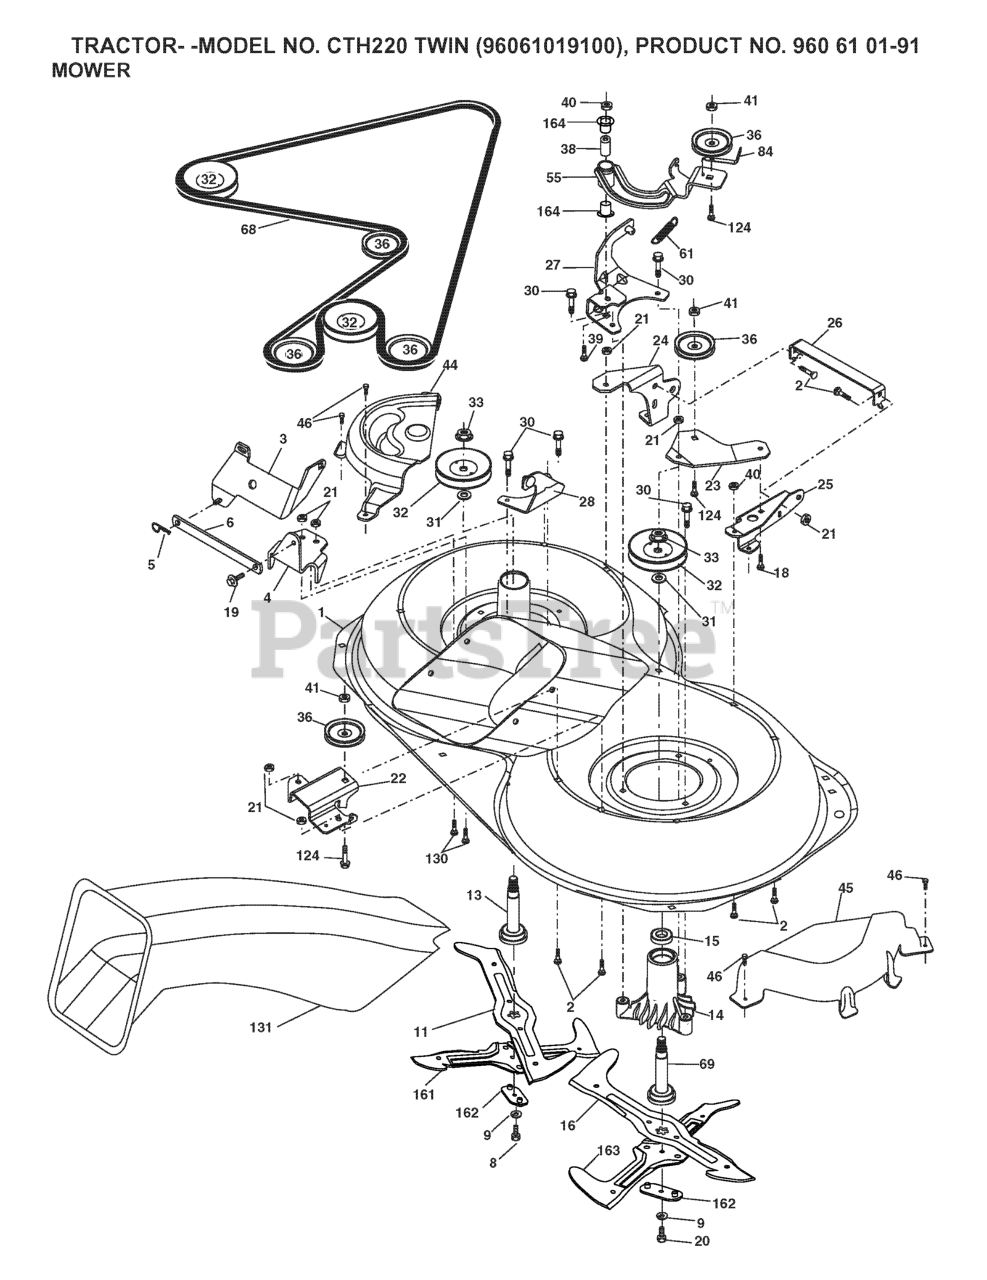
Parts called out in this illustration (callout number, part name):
1	Housing Asm. Mower 107 CRD
2	RP BOLT 5/16-18 X3/4 ZN/YEL GR
5	RETAINER-SPRNG RB
6	BAR.SWAY.92.CRD
8	BOLT.3/8-24X1.25 GR8
9	LOCKWASHER
11	BLADE.3N1.LH.CRD
13	SHAFT ASM VENT
14	HOUSING.MANDREL.VENTED (MACHD)
16	BLADE.3N1.RH.CRD
18	BOLT
19	BOLT SHD 5/16-18
20	BOLT.3/8-24X1.25GR8. LHTHRD
21	LOCKNUT
22	BRACKET.IDLER.RR.107.CRD
24	BRACKET
25	BRACKET RF
26	SUPPORT
28	BRACKET
30	SCREW, WASHER HEAD
31	WASHER.SPACER.MANDREL
32	PULLEY.MANDREL.4.80 PD.2006
33	NUT.FLANGE.LOCK.TOP
34	BRACKET
35	BRACKET
36	PULLEY.IDLER.4.25
41	NUT LOCK FLG 3/8-16 UNC
45	COVER.MANDREL.RH.CRD
46	SCREW.1/4-20X5/8
55	ARM.IDLER.107.CRD
61	SPRING
68	HEX-BELT 107 MOWER
69	SHAFT.ASM.W/LWR.BRG.RH.THREAD
84	KEEPER, BELT IDLER
116	BOLT.SHOULDER.3/8-16X3-5/8.
117	RP WHEEL. GUAGE RALLY
118	NUT LOCK FLG 3/8-16 UNC
119	WASHER
124	BOLT.3/8-16X1.50
130	BOLT.CARR.SQNK.5/16-18UNC.X3/4
131	CHUTE BAGGER
163	BLADE.CROSS.RH.CRD.107
164	BRNG T
